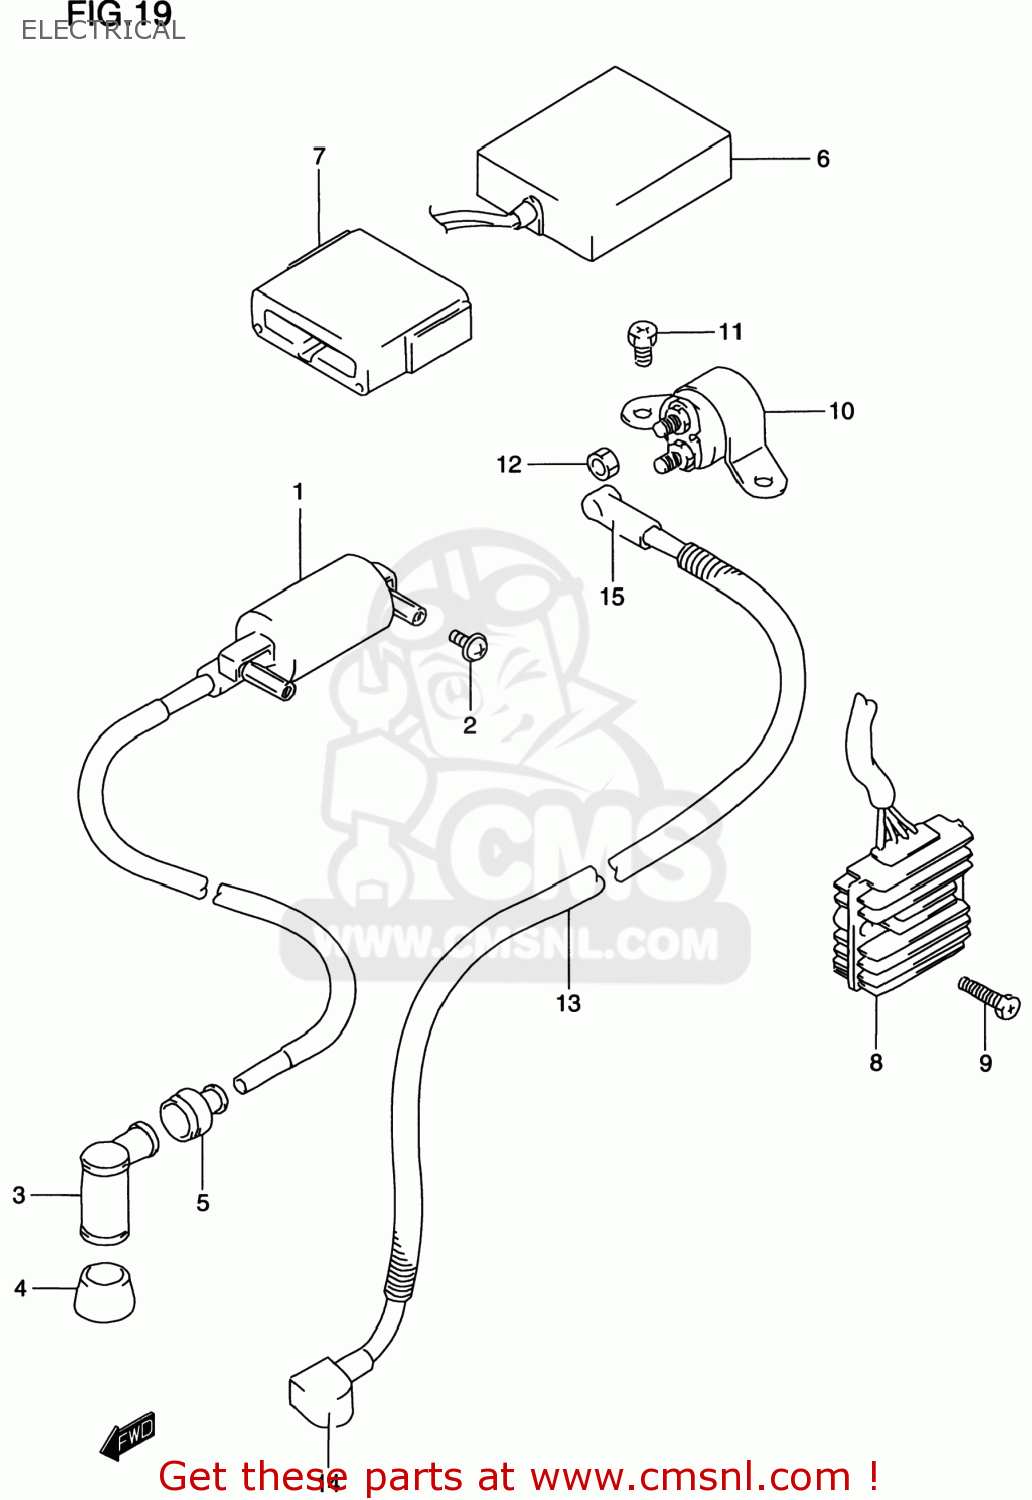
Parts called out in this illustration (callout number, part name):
1	COIL ASSY,IGNITION
2	SCREW
3	CAP ASSY,SPARK PLUG
4	SEAL,SPARK PLUG CAP
5	SEAL,HIGH TENSION CORD
6	IGNITOR
7	CUSHION,CDI UNIT
8	RECTIFIER ASSY
9	SCREW (6X25)
10	RELAY ASSY,STARTING MOTOR
11	SCREW(6X10)
12	NUT
13	WIRE,STARTER MOTOR LEAD
14	CAP,STARTER MOTOR TERMINAL
15	CAP,STARTER RELAY
